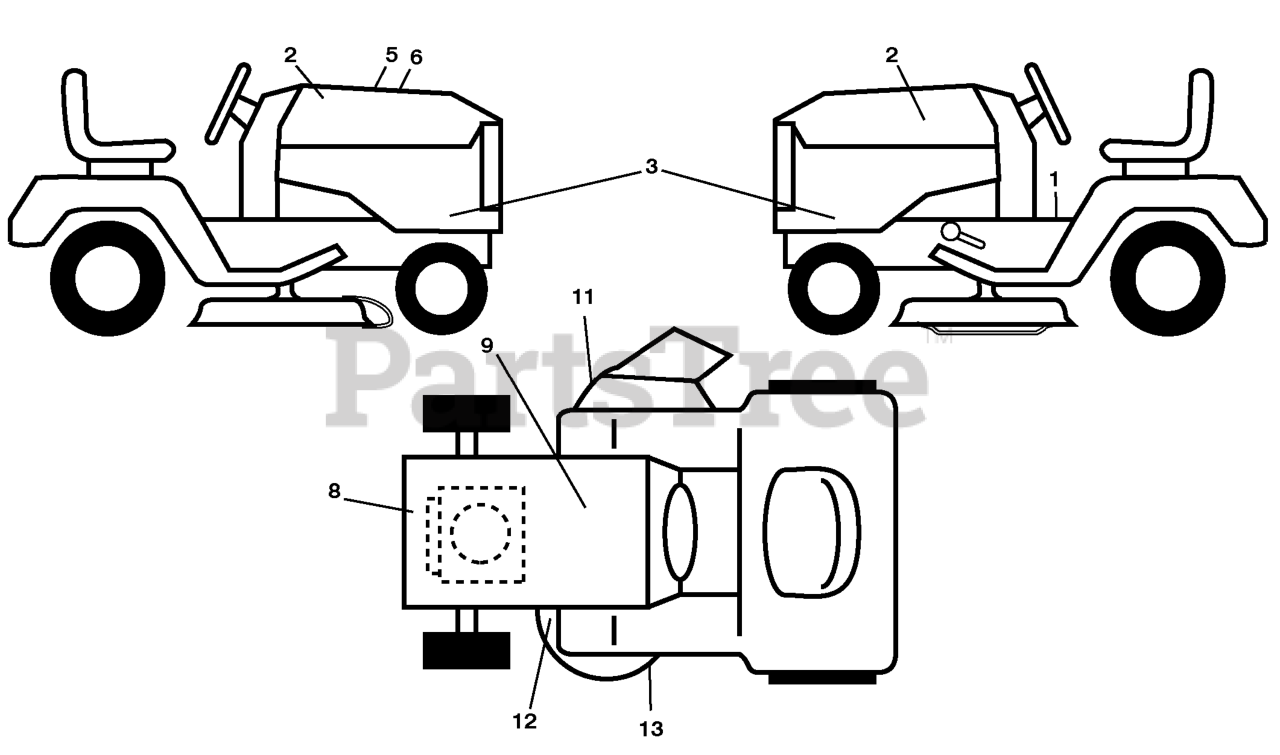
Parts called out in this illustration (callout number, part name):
1	DECAL.FENDER.WARNING.ENG
2	RP.DECAL.BADGE.170MM.TEXTLOGO
3	DECAL.SIDE PANEL.YTH23V48
5	DECAL.WARNING.CUST.RESP.E85.
6	Decal, Replacement
8	DECAL.ENG.BS.23HP.XRD.TWIN
9	DECAL BTRY SYMBOLS
11	DECAL.WARN.KEEP.HAND.AWAY
12	DECAL.MOWER
13	DECAL.MOWER.SCH.48/54
